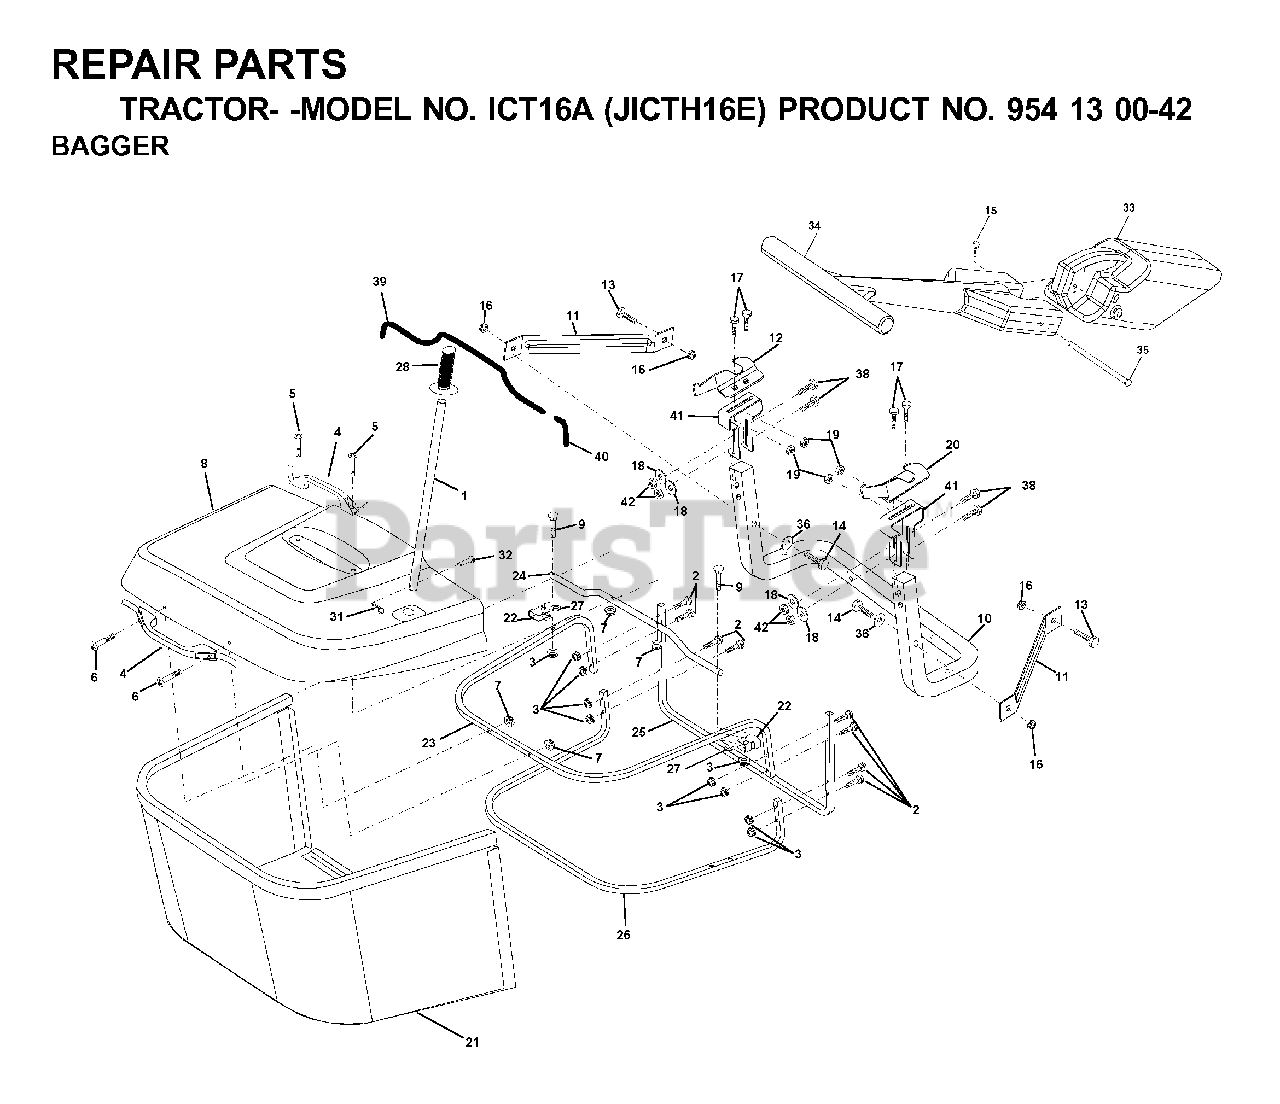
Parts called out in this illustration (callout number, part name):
1	TUBE HANDLE BAGGER
3	NUT T
5	SCREW.PAN.HEAD
10	TUBE
11	BRACKET
15	RETAINER-SPRNG RB
16	NUT LOCK FLG 3/8-16 UNC
17	BOLT
18	WASHER M
19	NUT LOCK HEX FLANGE 5/16-18
20	BRACKET
21	BAG
22	BRACKET
23	TUBE
24	TUBE
26	TUBE
31	RETAINER M
32	RIVET,DRILLED
33	MULCH PLUG, CTH150
35	PIN
36	WASHER
38	BOLT.5/16-18X2.5
39	TRIM
40	TRIM
41	BRKT, BAGGER
42	NUT.71038.31-18.HEX.NYLOCK
